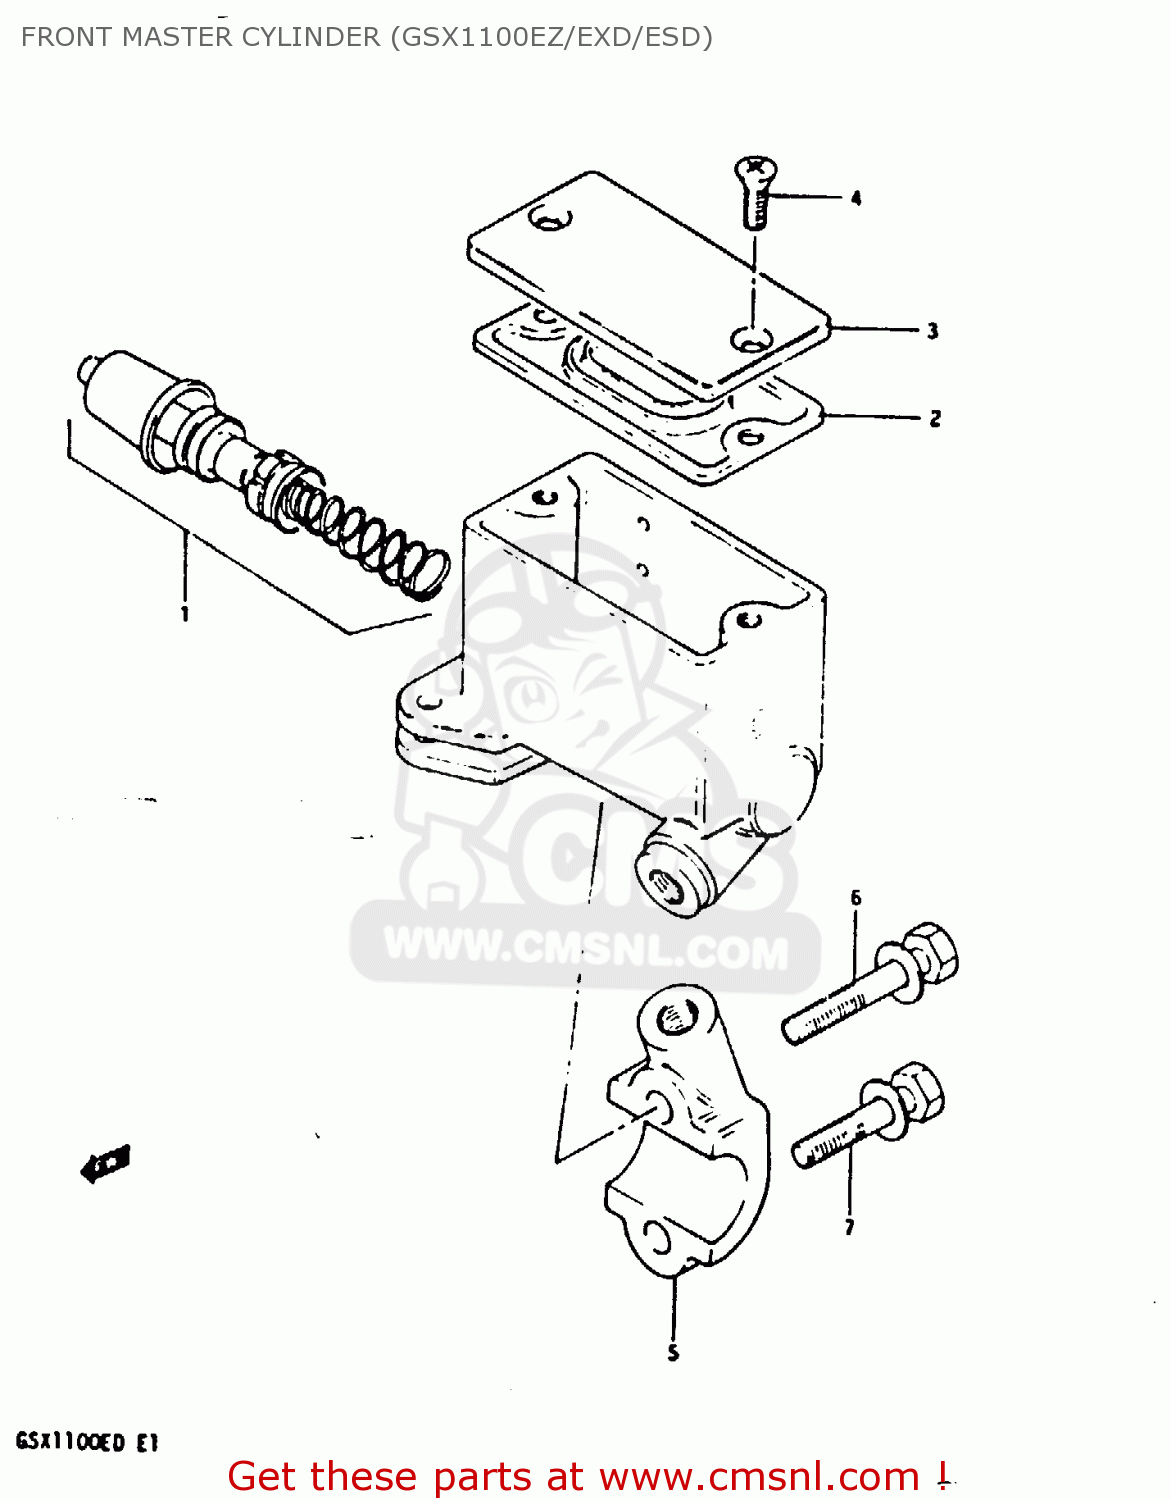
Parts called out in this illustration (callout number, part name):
1	PISTON & CUP SET
2	DIAPHRAGM,MASTER CYLINDER
3	CAP
4	SCREW,RESERVOIR CAP
5	HOLDER
6	BOLT,MASTER CYLINDER H
7	BOLT,MASTER CYLINDER H
